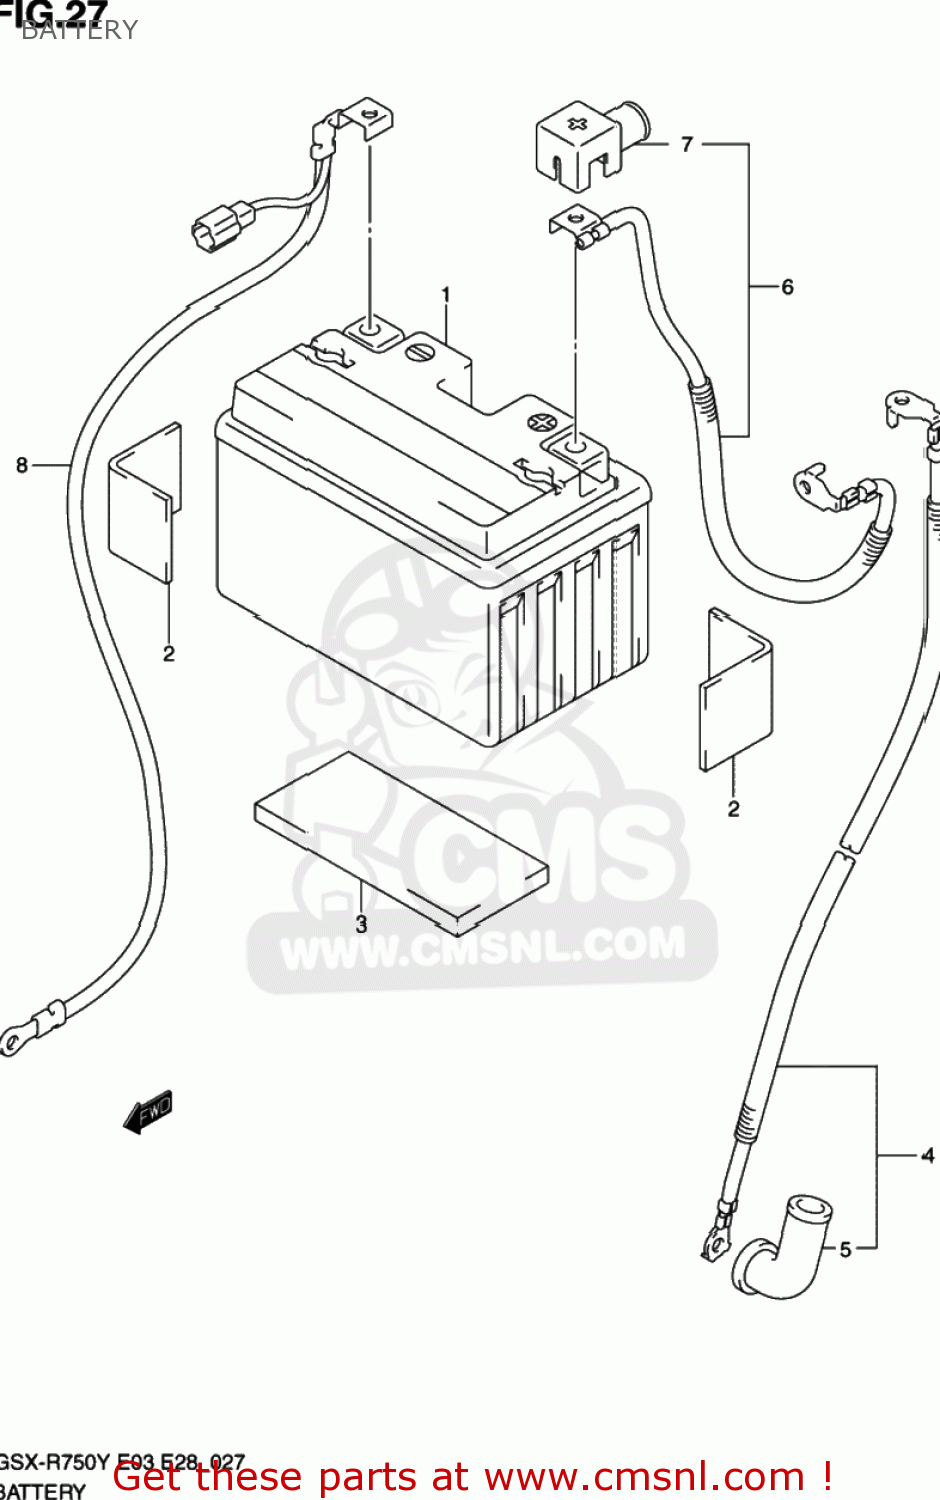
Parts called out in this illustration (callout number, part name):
1	BATTERY ASSEMBLY (12V) YT1
2	PROTECTOR(170X95X3.0)
3	PROTECTOR,BATTERY
4	WIRE,STARTER MOTOR LEAD
5	CAP,STARTER MOTOR LEAD
6	WIRE,BATTERY PLUS LEAD
7	CAP,BATTERY PLUS
8	WIRE,BATTERY MINUS LEAD
